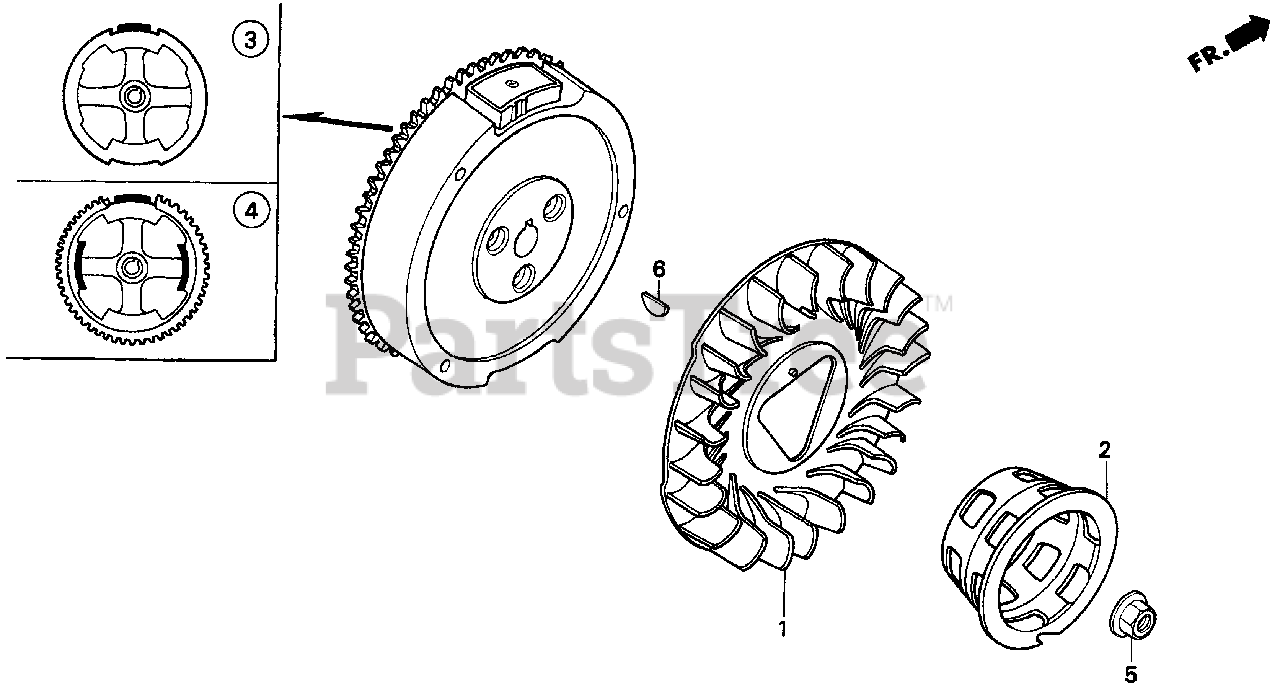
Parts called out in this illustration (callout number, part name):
1	FAN, COOLING
2	PULLEY, STARTER
3	FLYWHEEL
5	NUT, SPECIAL (16MM)
6	KEY, SPECIAL WOODRUFF (25X18)
